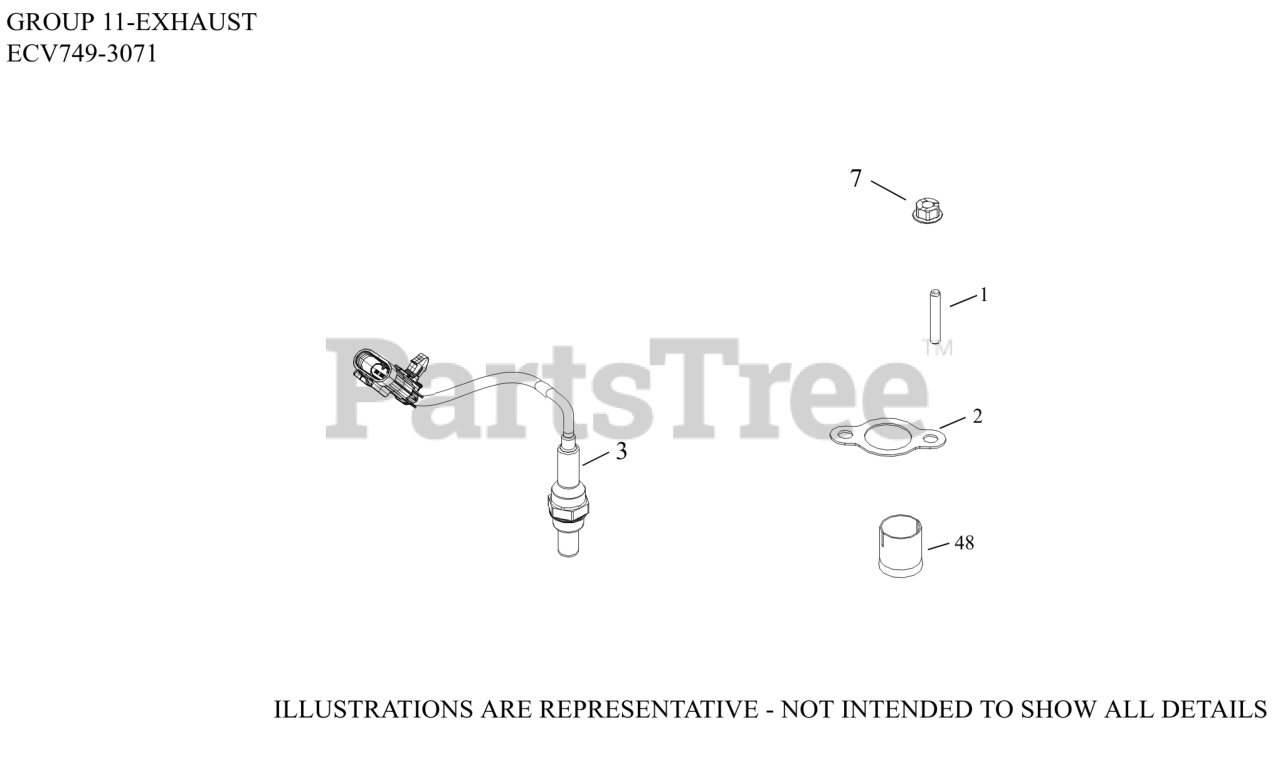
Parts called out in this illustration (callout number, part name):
2	GASKET, EXHAUST
3	SENSOR, OXYGEN (M18 x 1.5 THREADS)
7	NUT, HEX FLANGE LOCK (M8)
48	LINER, EXHAUST PORT
